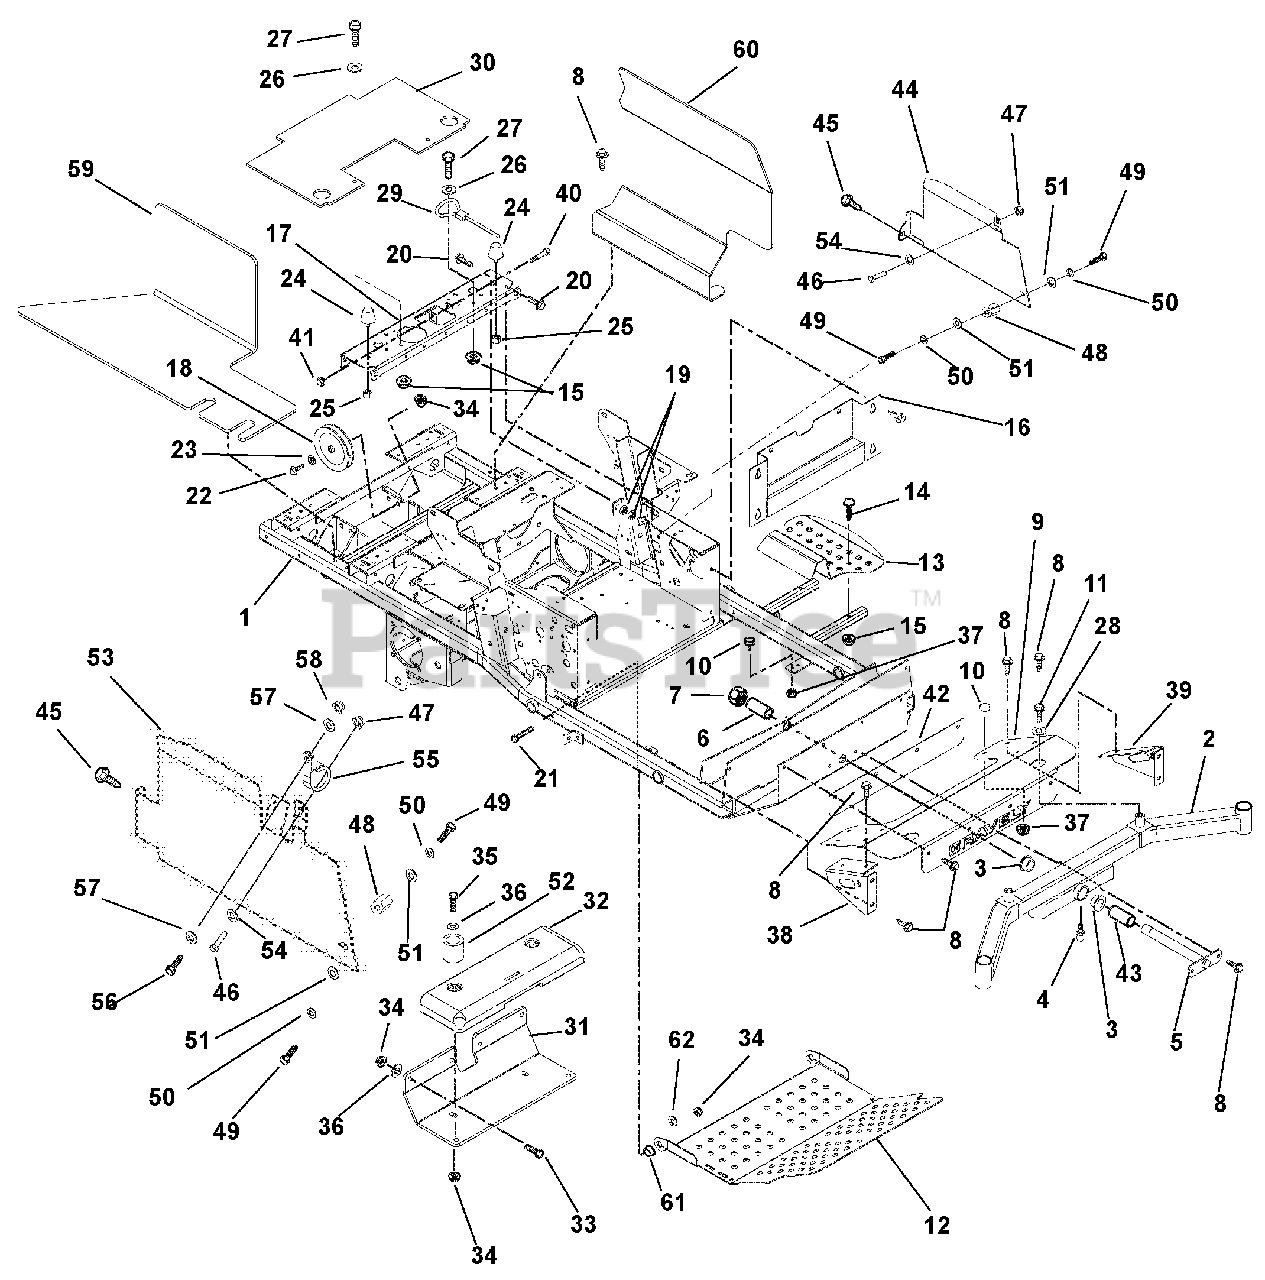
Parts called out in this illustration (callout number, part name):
1	Weldment, Frame
2	Weldment, Front Axle
3	Bushing, Flange 1.25 x 1.50 x 1.00 x .200
4	Fitting, Lube 45 Degree GM411031
5	Pin, Axle
7	Nut, Locking Nylon 1.0-14
8	Screw, Tapping .38-16 x .75
9	Axle Cover
10	Button, Bumper
11	Bolt, Hex .50-20 x 1.00 Grade 5
12	Panel, Inspection
13	Step, Ingress
14	Bolt, Round Head Square Neck .31-18 x 1.75 Grade 5
15	Nut, Locking Top Flange .31-18
16	Plate, Kick
17	Channel, Cross
18	Pulley, Idler
19	Nut, Retainer .375-16 x .37
20	Bolt, Serrated Flange Washer Head .38-16 x 1.00
21	Bolt, Hex .50-13 x 3.25 Grade 5
22	Bolt, Hex .50-13 x 2.25 Grade 5
23	Washer, Flat Steel .505 x .88 x .072
25	Nut, Spin Lock Flange .312-18
26	Washer, Flat Steel .064 x 1.810 x .250
27	Bolt, Hex .31-18 x 1.00 Grade 5
28	Washer, Flat Steel .64 x 1.75 x .250
29	Cable, Seat Prop
30	Guard, Grass
31	Bracket, Support Arm
32	Weight, Cast Iron
33	Bolt, Hex .50-13 x 1.25 Grade 5
34	Nut, Locking Top Flange .50-13
35	Bolt, Hex .50-13 x 4.50 Grade 5
36	Washer, Flat Steel .531 x 1.06 x .095
37	Nut, Spin Lock, Flange .312-18
38	Weldment, Axle Cover Support Right Hand
39	Weldment, Axle Cover Support Left Hand
40	Bolt, Hex .38-16 x 3.00 Grade 5
41	Nut, Locking Top Flange .38-16
42	Plate, Backer
43	Spacer, 1.25 OD x 1.0 ID x 3.63
44	Plate, Guard, Debris
45	Screw, Tapping Hex Washer Head .38-16 x .50 TR
46	Bolt, Hex Washer Head .25-20 x .75 Grade 5
47	Nut, Nyloc, Flanged, .25-20
48	Nut, Coupling .31-18 x 2.25 LG
49	Bolt, Hex .31-18 x .75 Grade 5
50	Washer, Locking .31 x .078 Reg
51	Washer, Flange, Steel .344 x .688 x .065
52	Spacer, .563 x 6.25 x .969
53	Bracket, Guard Right Hand
54	Washer, Plated, Steel
55	Clamp, Steel
56	Bolt, .38-16 x 1.25 Grade 5
57	Washer, Flat Steel .406 x .812 x .065
58	Nut, Locking Top Flange .38-16
59	Guard, Diesel Left Hand
60	Guard, Diesel Right Hand
61	Bushing, Flange .515 x .75 x .275
62	Washer, Flat Steel .563 x 1.38 x .109
